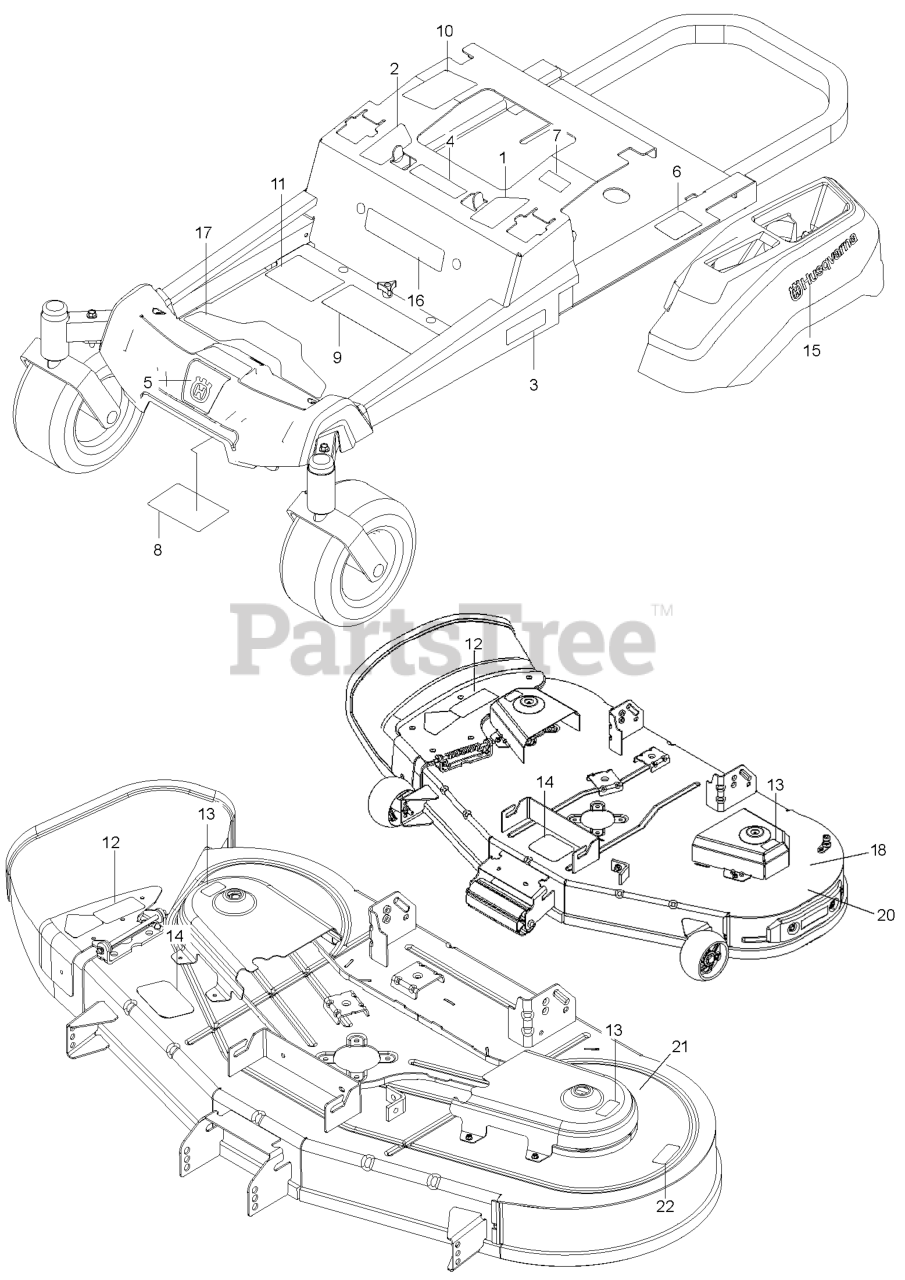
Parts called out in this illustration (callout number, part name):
1	DECAL.ZTR.RZ.THRTL/PRKBRK.V2.L
2	DECAL.ZTR.RZ.THRTL/PRKBRK.V2.R
3	DECAL ZTR SIDE RAIL GRAPHIC DE
4	EURO DECAL-BATTERY WARNIN6
5	DECAL.BADGE.55MM.CROWNH.HUSQ
6	DECAL, DO NOT TOW
7	DECAL, EXITING MOWER
8	DECAL, SERVICE
9	DECAL ZTR WARNING DECAL DECAL.
10	DECAL.WARNING.CUST.RESP.E85.
11	DECAL.ZTR.STARTINSTRCT.CHOKE15
11	DECAL ZTR BRAND GRAPHIC DECAL.
11	DECAL.ZTR.STARTINS.READYSTART
12	DECAL.TRACT/ZTR.DECKWARN.HUSQ
13	DECAL.DECK.CLEARCUT.NOSTEP
14	DECAL BELT ROUTING DECAL DECAL
15	DECAL.HUSQVARNA.210MM
16	DECAL ZTR BRAND GRAPHIC DECAL.
17	PAD.RZ.FOOTREST.PLATE
18	DECAL DECK DECAL DECAL.DECK.WA
20	DECAL.54DECK.CLEARCUT.VER2.18
21	DECAL DECK DECAL DECAL.DECK.WA
22	DECAL.54DECK.CLEARCUT.VER2.18
